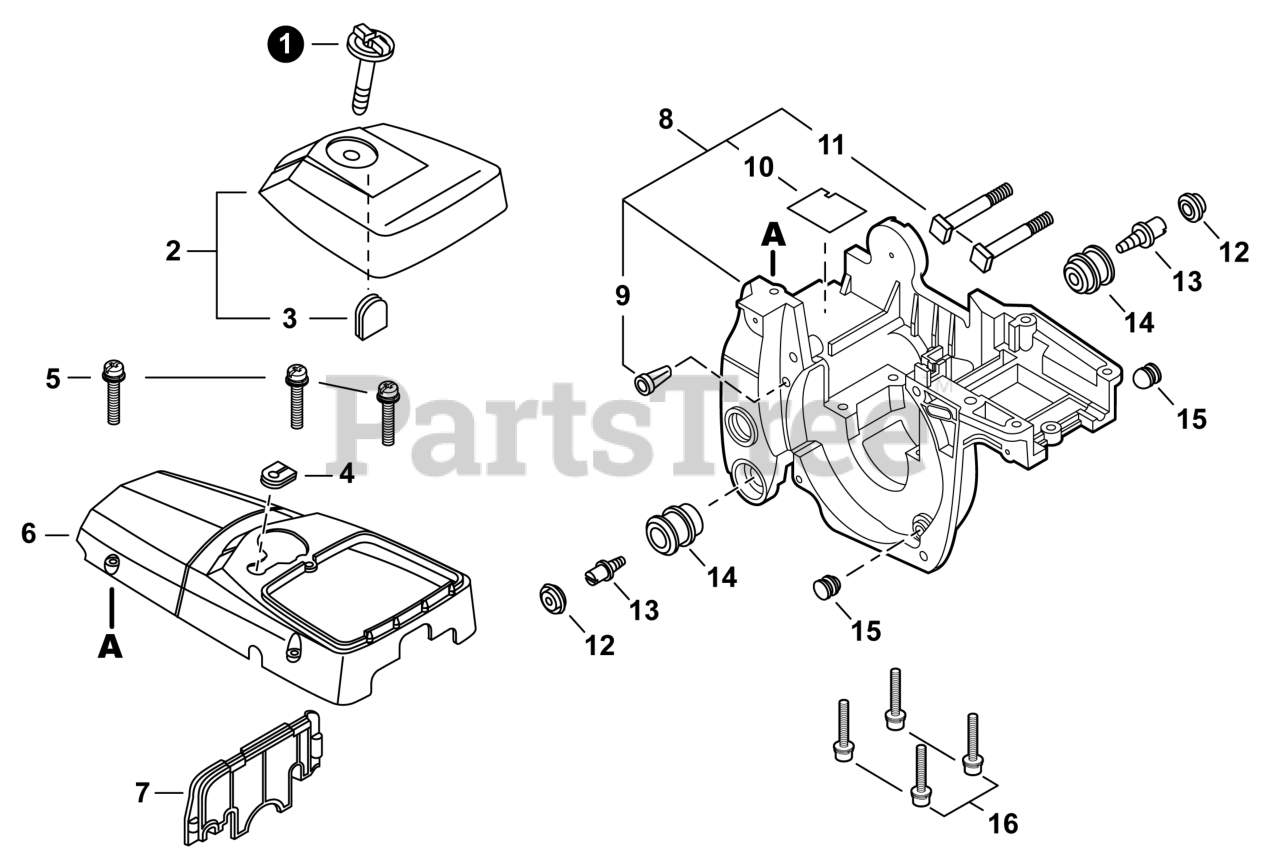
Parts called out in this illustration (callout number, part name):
1	THUMBSCREW
2	COVER ASSY, AIR FILTER
4	GROMMET
5	SCREW 5×20
6	COVER, ENGINE
7	PLATE, INSULATOR
8	COVER ASSY, ENGINE
9	CHECK VALVE
10	SHIELD, HEAT
11	STUD, GUIDE BAR 8
12	CAP, CUSHION
14	CUSHION 5
15	CUSHION
16	BOLT 5×30
